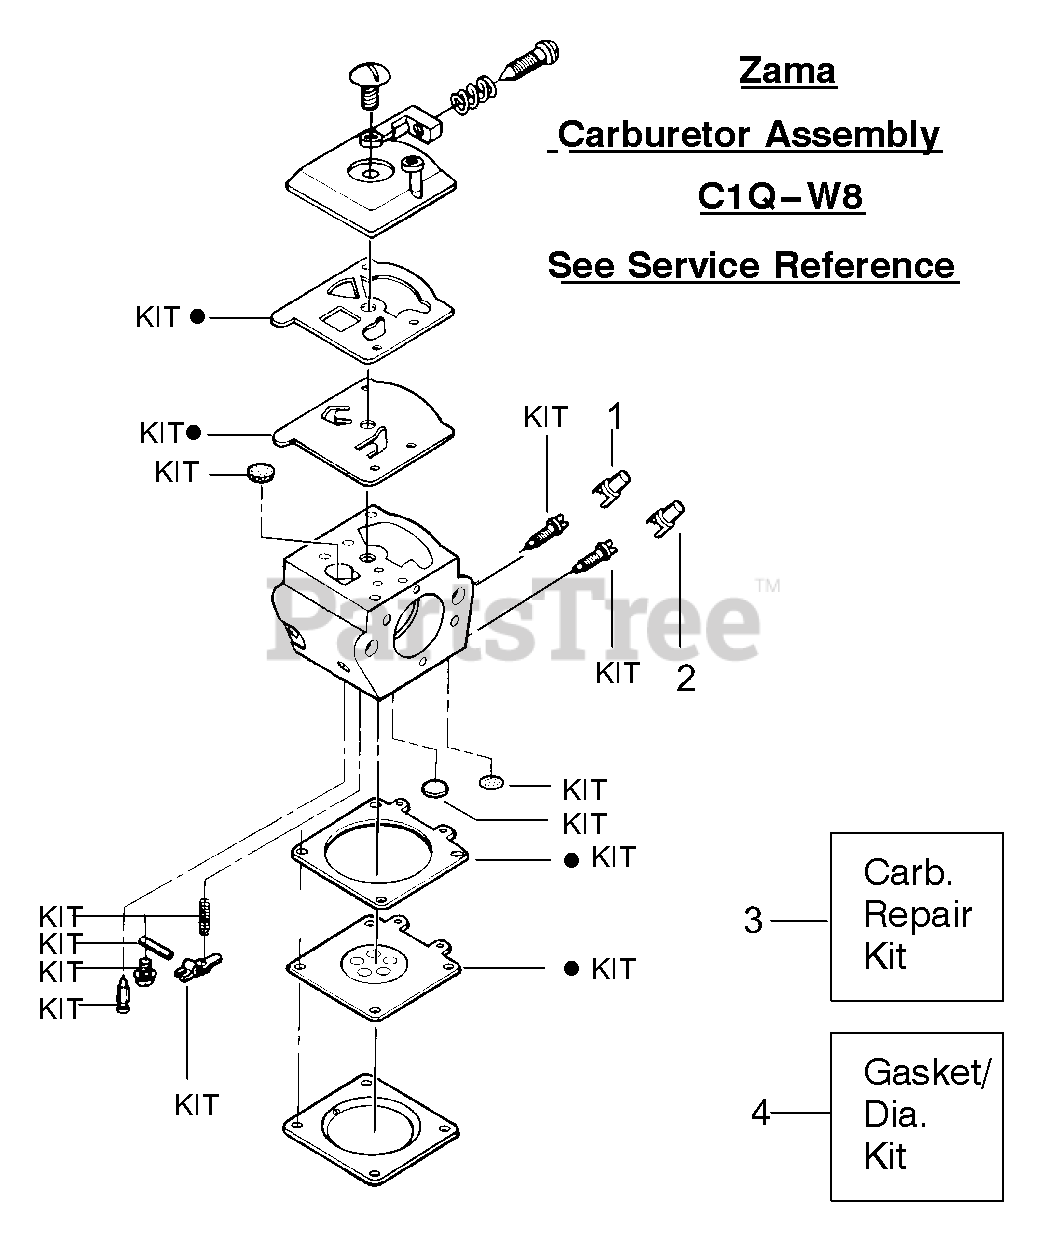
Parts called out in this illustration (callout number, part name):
1	Limiter Cap High (brown)
2	Limiter Cap Low (tan)
3	Carburetor Repair Kit Zama (C1Q-W8)
4	Gasket Diaphragm Kit Zama (C1Q-W8)
